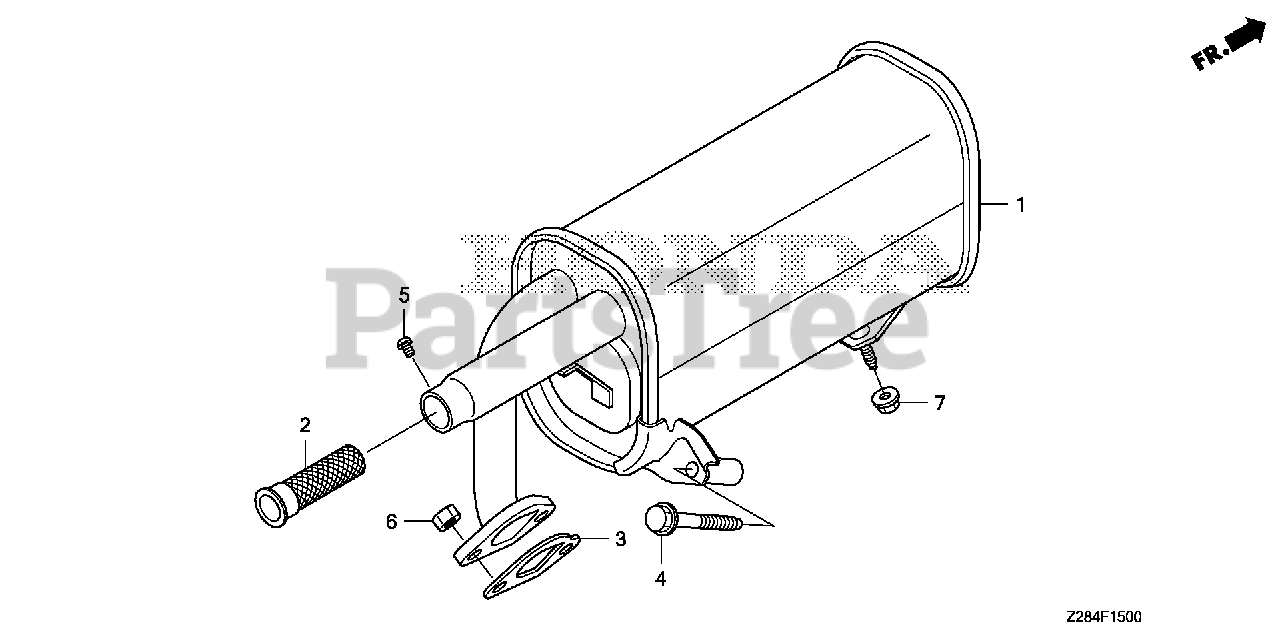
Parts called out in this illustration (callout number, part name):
1	MUFFLER
2	ARRESTER, SPARK
3	GASKET, MUFFLER
4	BOLT, FLANGE (6X47) (CT200)
5	SCREW, TAPPING (4X6) (TO INSTALL OPTIONAL SPARK ARRESTER)
6	NUT, HEX. (8MM)
7	NUT, FLANGE (6MM)
